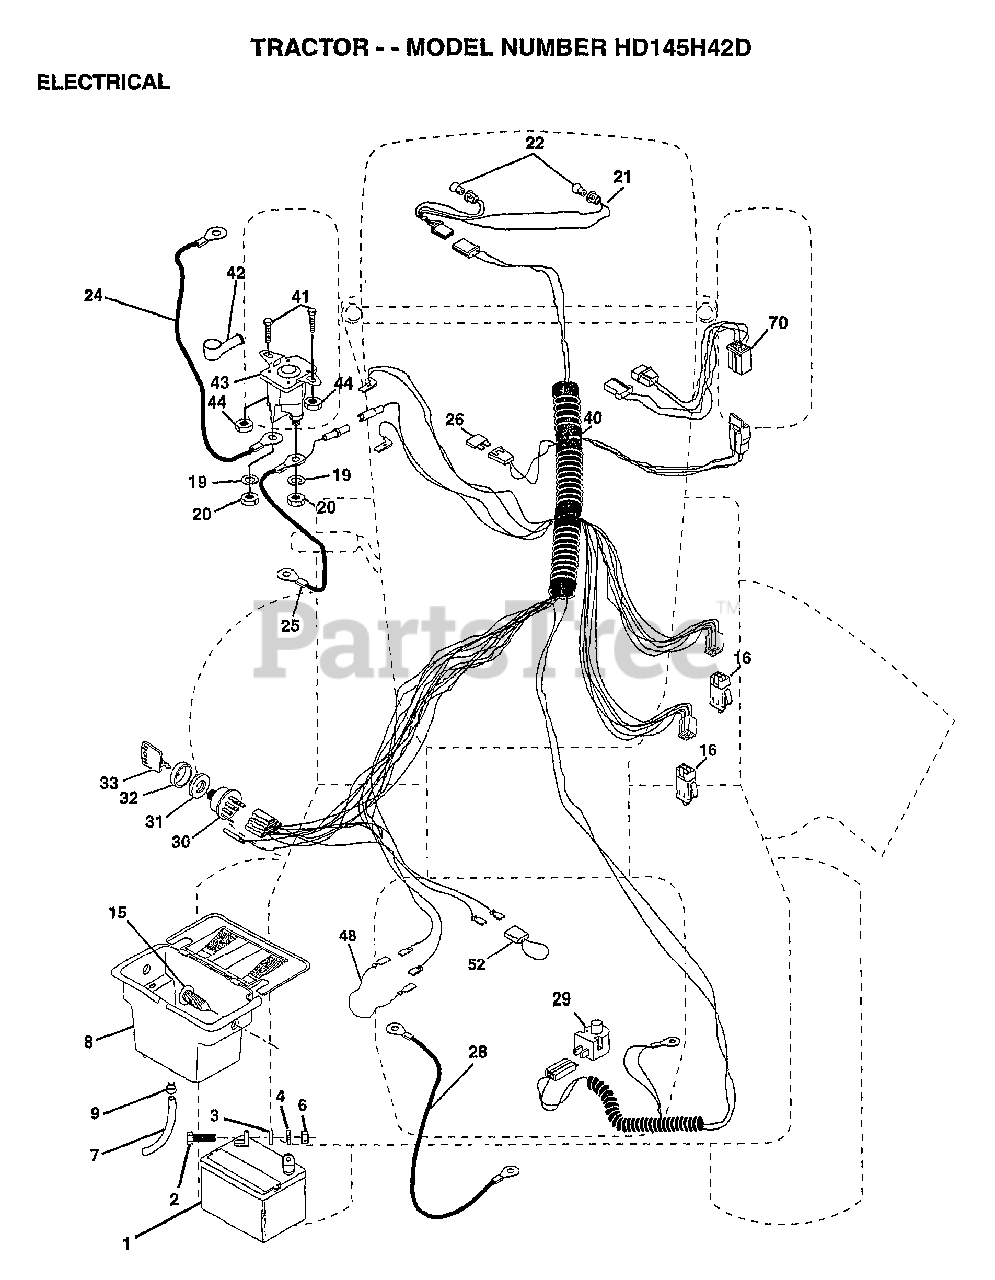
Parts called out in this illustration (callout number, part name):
2	BOLT LT
3	WASHER
4	LOCKWASHER
7	TUBE T
8	"CASE,BATTERY.MECH"
9	HOSE CLAMP T
15	FASTNER.SNAP-IN
16	SWITCH INTERLOCK
20	NUT
21	"HARNESS,LIGHT SOC"
22	HEADLAMP BULB
24	"CABLE T, BATTERY"
25	CABLE.BTRY.6GA.RD
26	FUSE HYT
28	CABLE T
29	SWITCH SEAT
30	SWITCH IGN 4POS
31	NUT IGNITION
32	COVER KEY SWITCH
33	KEY
40	HARNESS-IGNITION
41	BOLT HXHD FIN
44	NUT HXKEP 1/4X20
48	ADAPTER AMMETER
52	PROTECTION LOOP
70	HARNESS.ENG.DUAL
